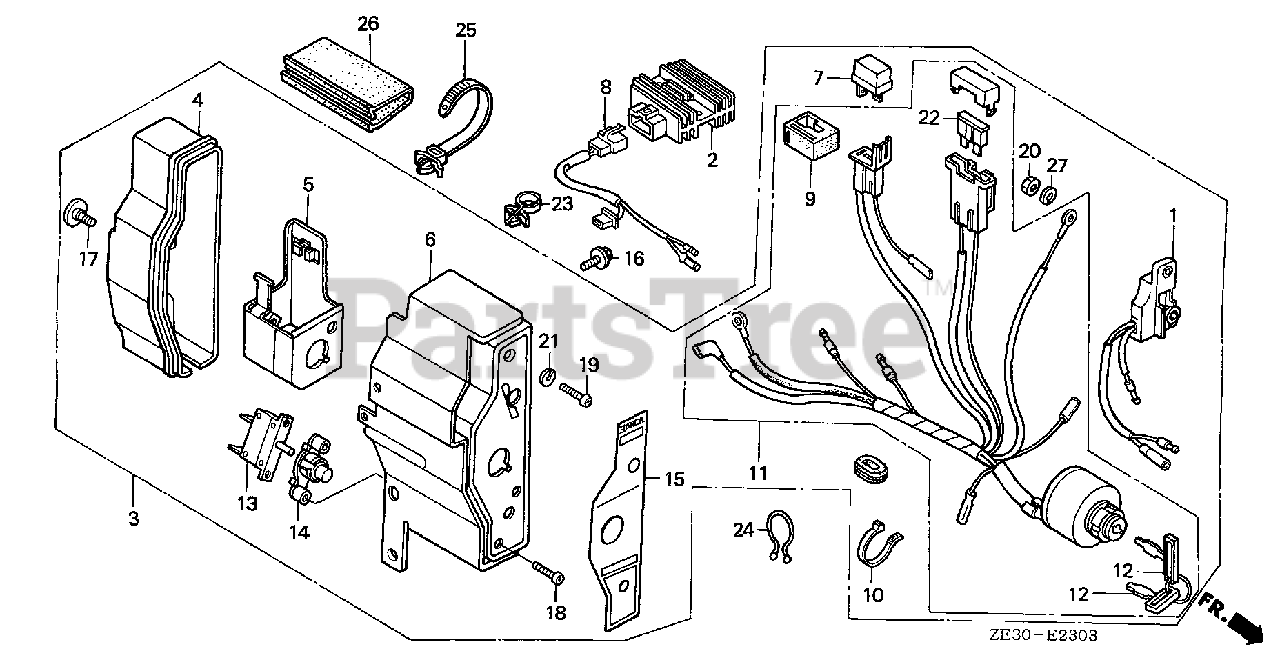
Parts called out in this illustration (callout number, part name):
1	ALERT UNIT, OIL (NOT AVAILABLE)
2	RECTIFIER ASSY., REGULATOR (10A)
3	BOX ASSY., CONTROL (EXTERNAL-ALERT-10A)
3	BOX ASSY., CONTROL (EXTERNAL-ALERT/10A) *R8* (BRIGHT RED) (NOT AVAILABLE)
4	CASE, CONTROL
5	BRACKET, CASE MOUNTING
6	PANEL, CONTROL *R280* (POWER RED)
8	SUB-WIRE HARNESS ASSY.
10	BAND
11	SWITCH ASSY., COMBINATION (10A-CHARGE)
12	KEY (HONDALOCK)
15	MARK, CONTROL BOX (EXTERNAL-ALERT)(REGULATOR) (NOT AVAILABLE)
16	BOLT, FLANGE (6X12) (CT200)
17	SCREW, SPECIAL (6X12)
19	SCREW, PAN (4X12)
20	NUT, HEX. (4MM) (SOURCE: VINTAGE PARTS INC.)
21	WASHER, SPRING (4MM)
22	FUSE, BLADE (15A)
23	HOLDER, STOP SWITCH WIRE
24	CLIP, PURSE LOCK
25	STRAP, CABLE (118MM) (BLACK)
26	TUBE, FASTENER (30MM)
